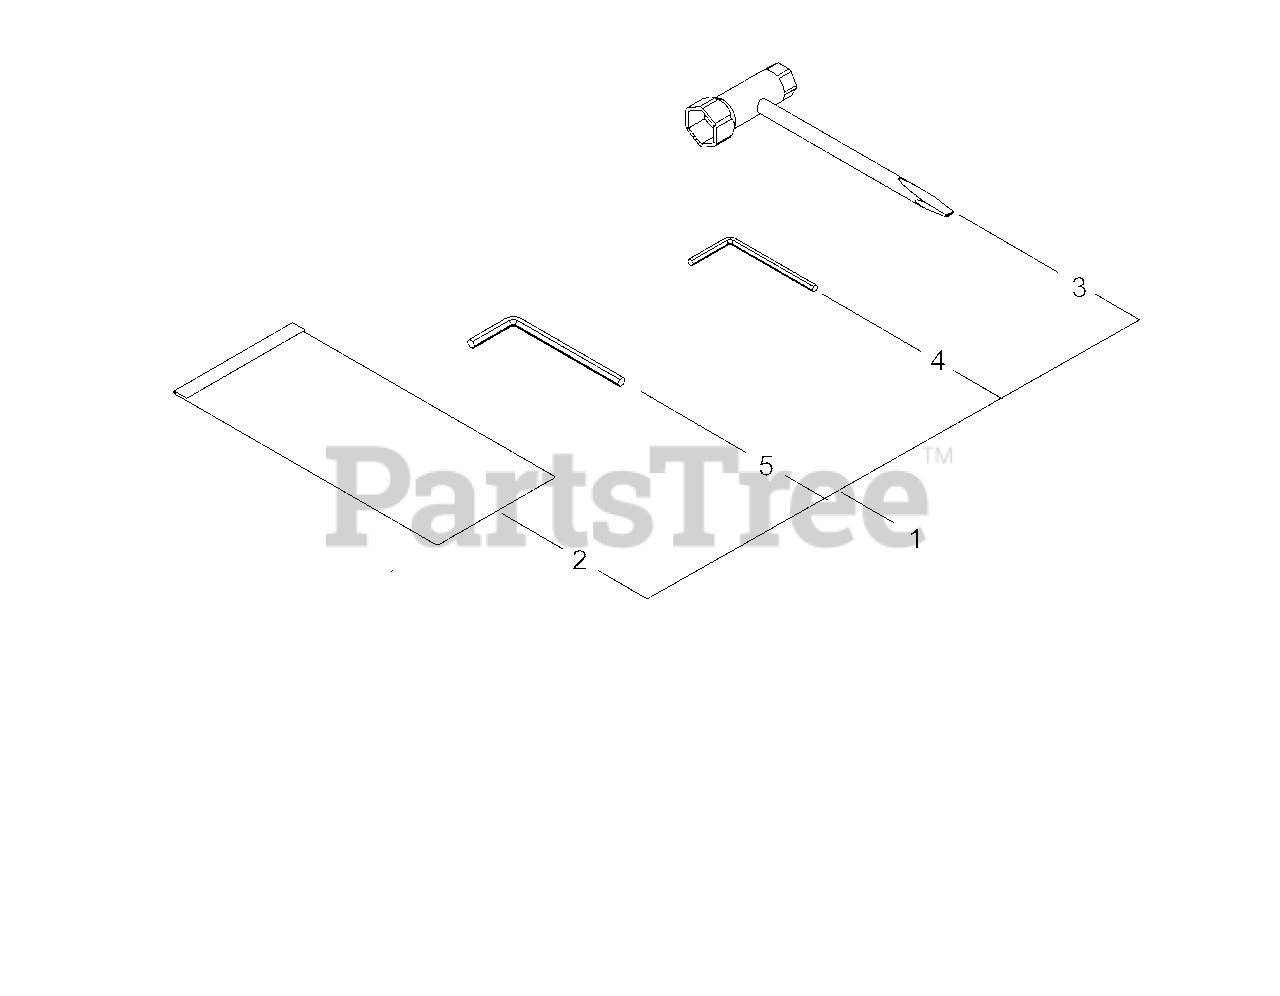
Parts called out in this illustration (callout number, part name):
1	TOOL KIT, SERVICE
2	BAG, TOOL
3	T-WRENCH 17×19 MM
4	WRENCH, ALLEN 4 MM
5	WRENCH, ALLEN 5 MM
